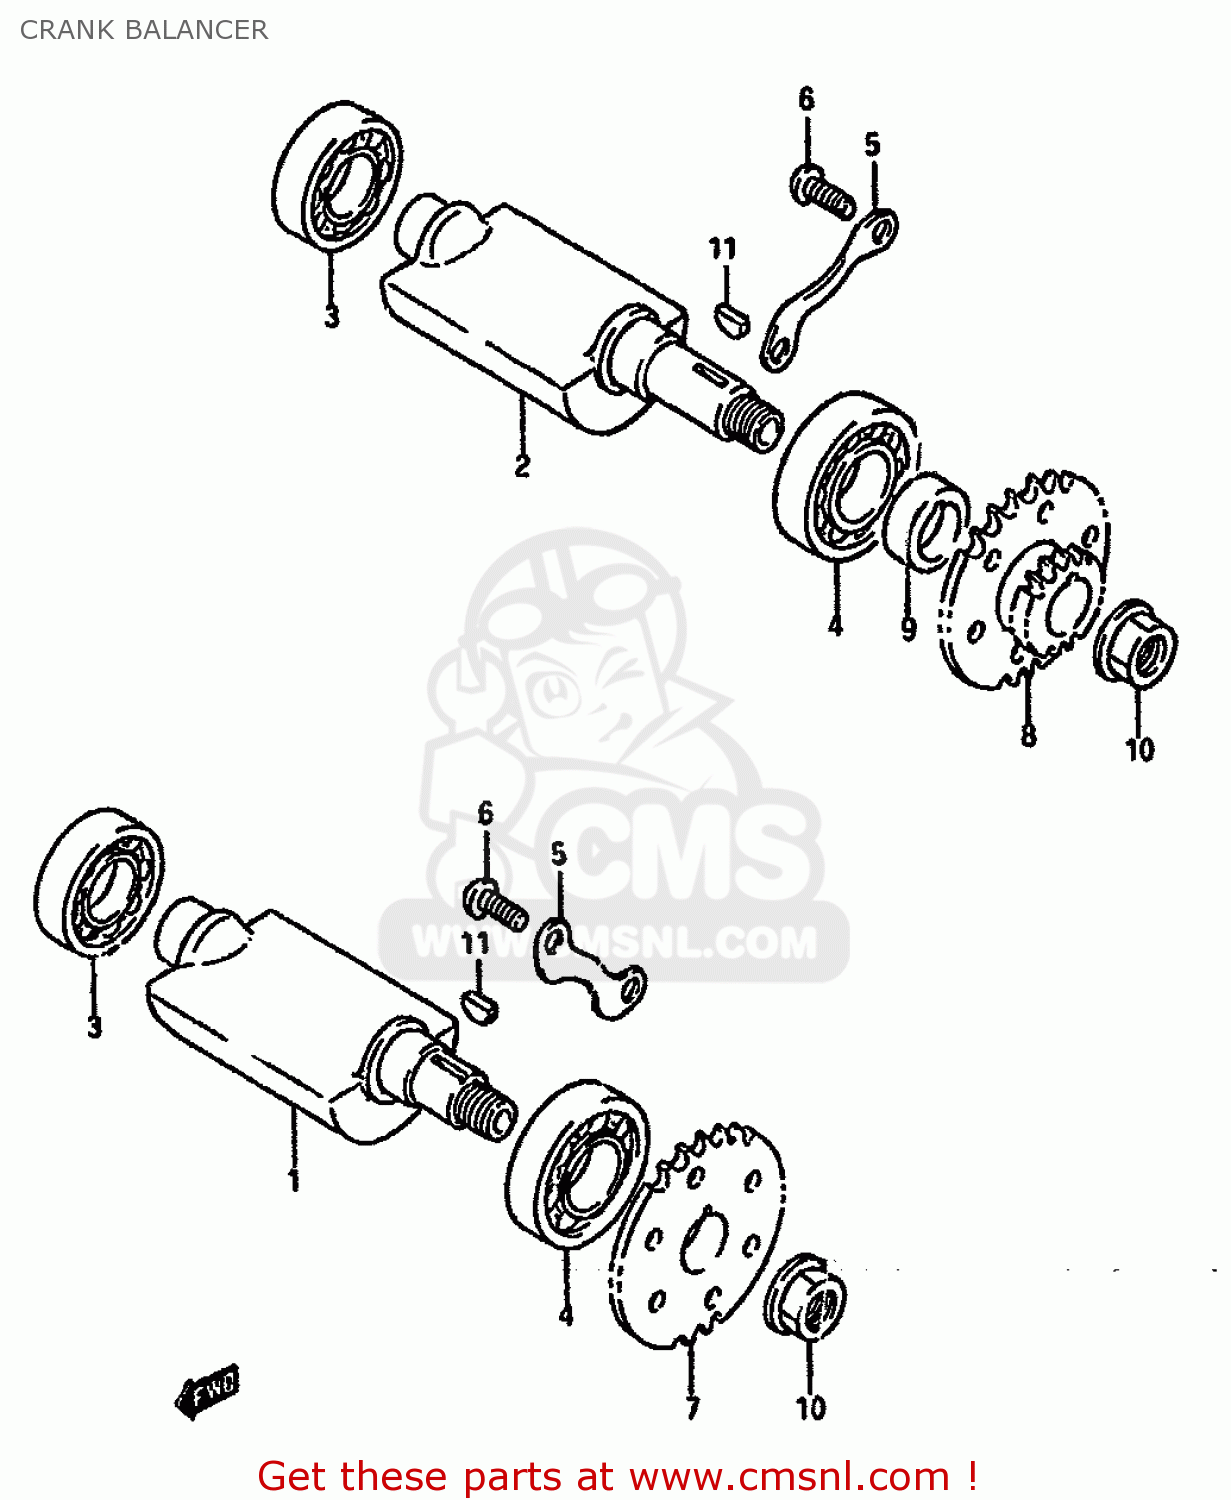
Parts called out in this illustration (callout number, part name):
1	BALANCER,CRANK,FRONT
2	BALANCER,CRANK,REAR
3	BEARING(20X42X12)
4	BEARING 20X47X14
5	RETAINER,CRANK BAL BEARING
6	SCREW
7	SPROCKET,BALANCER DRIVEN FR
8	SPROCKET,BAL.R
9	SPACER,CRANK BAL RR
10	NUT
11	KEY
